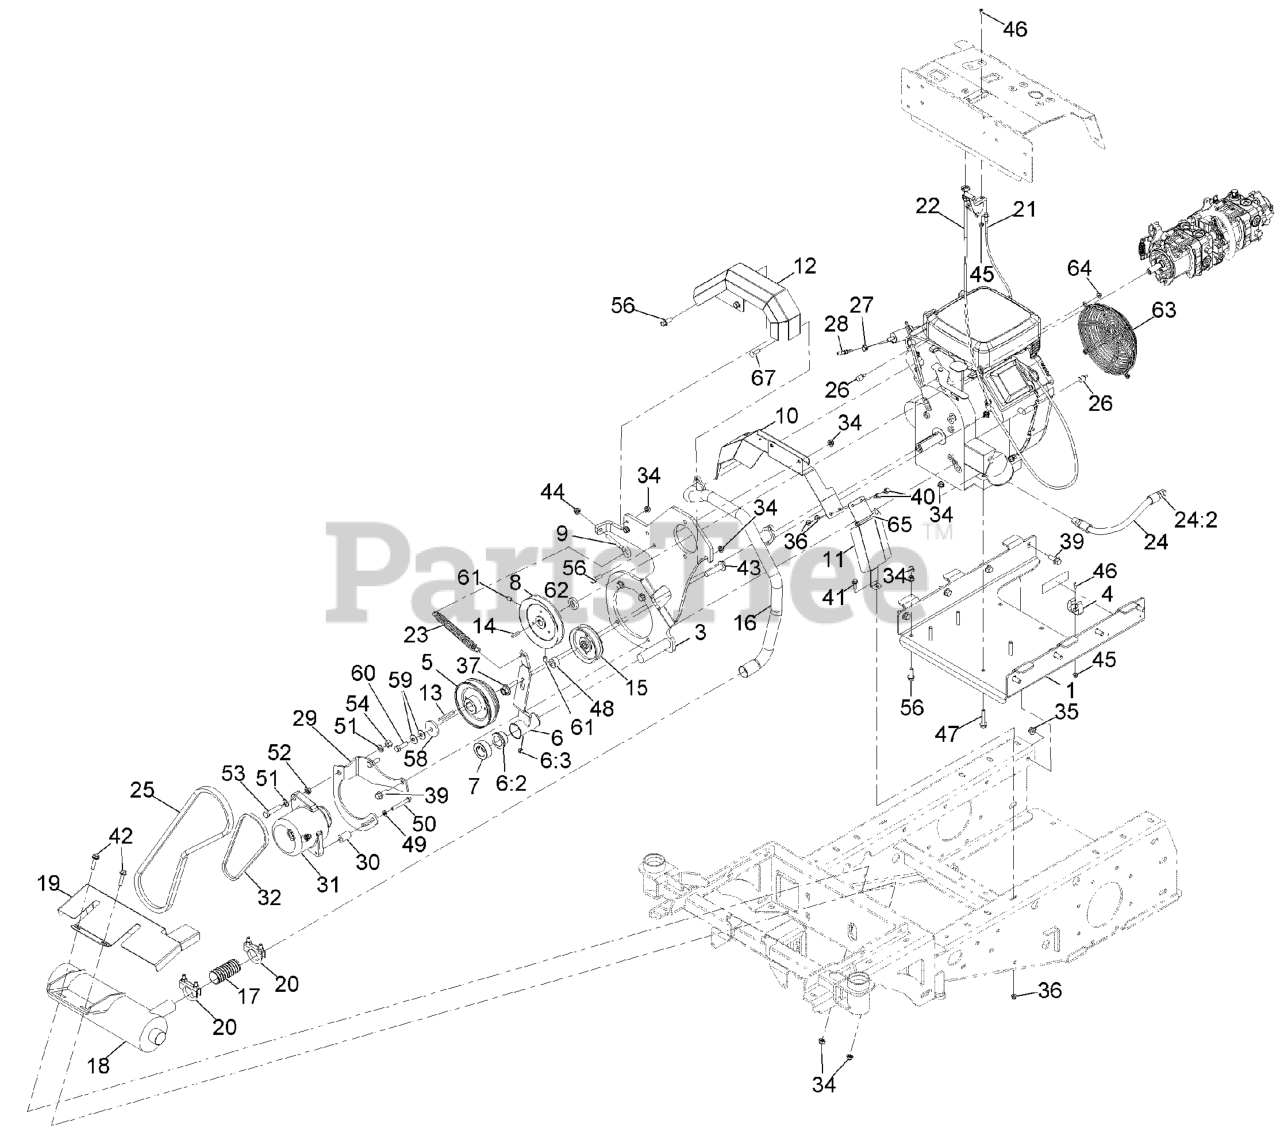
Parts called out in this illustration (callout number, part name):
1	Tray-Engine
3	Bracket-Engine, Pump [black]
4	Holder-Tool, Clip
5	Pulley-Double
6	Arm-Tension, ASM
6:2	BUSHING-FLANGE
6:3	FITTING-GREASE, ZERK
8	PULLEY-DRIVE, PUMP
9	Bolt-Eye
10	Guard, Lower Muffler
11	Guard, Lower Muffler
12	Guard-Pulley
15	PULLEY-IDLER, FLAT
16	Manifold-Exhaust
17	TUBE-EXHAUST, FLEX
18	MUFFLER
19	SHIELD-HEAT, MUFFLER
20	Clamp-Muffler
21	CABLE-THROTTLE
22	CABLE-CHOKE
23	SPRING-EXTENSION
24	ASM, Oil Drain Hose W/Plug
26	Tube-Heat Shrink, 1/2
27	CLAMP-HOSE
28	BARB-FUEL
29	Bracket-Alternator
30	TUBE-SUPPORT, ALTERNATOR
31	ALTERNATOR
32	Belt-V, 3L240
34	Nut-Hex Flange
35	Nut-Hex Flange
36	Nut-Hex Flange
37	Nut-Lock 1/2-13
39	SCREW-HHF
40	SCREW-HHF
41	Screw-HHF
42	SCREW-HHF
43	Screw-HHF
44	NUT-HF, NI
45	Nut-Hex Flange
46	Screw-HSBH
47	Screw-HHF
49	WASHER-LOCK
50	Screw-HH
51	Washer-Flat
52	Nut-Hex
53	Screw-HH
54	Nut-Lock, NI
56	SCREW-HHF
58	WASHER-PLAIN
59	WASHER-BELLEVILLE
60	Screw-HH
61	Setscrew-HSH
63	GUARD-WIRE, VANGUARD
65	TIE-CABLE
67	Bolt,Carriage,5/16-18X1,ST/ST 18-8
